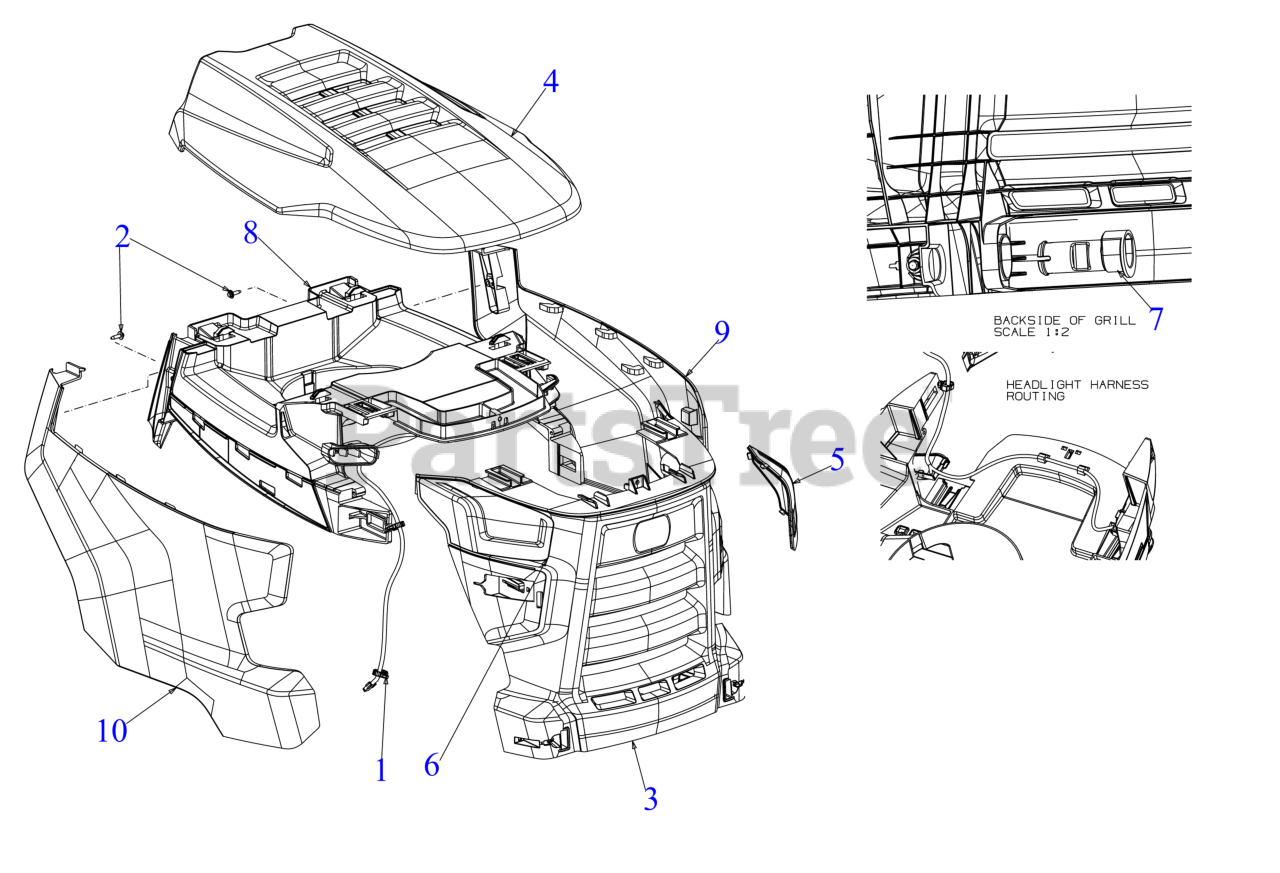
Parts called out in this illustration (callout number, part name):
1	HEADLIGHT HARNESS (W/LED)
2	SCREW 1/4-10 x .750
3	FRONT GRILLE (STYLE C)
4	HOOD TOP
5	LED HEADLIGHT LENS (LH)
6	LED HEADLIGHT LENS (RH)
7	HOOD PIVOT PIN
8	PLENUM/HOOD FRAME W/O LABEL
9	SIDE PANEL (LH)
10	SIDE PANEL (RH)
